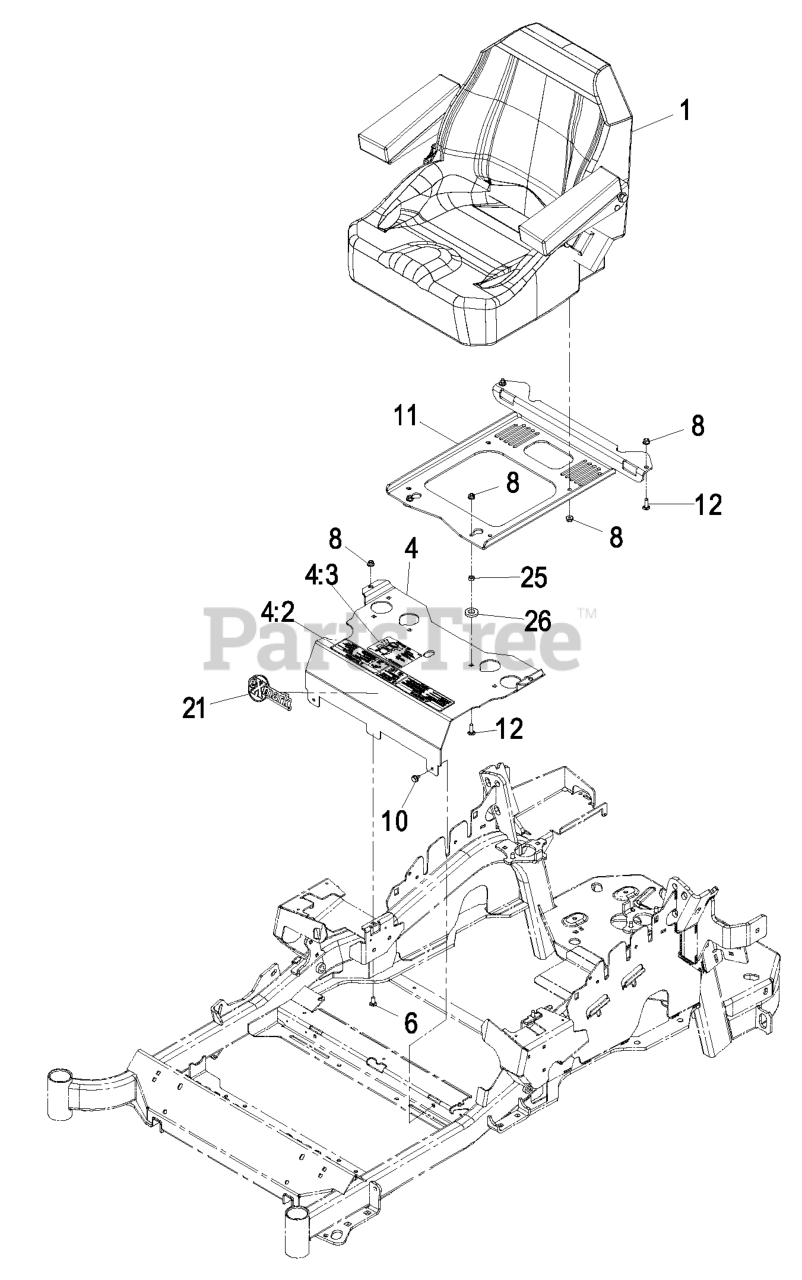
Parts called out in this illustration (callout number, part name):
4	MOUNT-SEAT
4:2	DECAL-CONSOLE
4:3	DECAL-SERVICE AID
6	SCREW-CARR
8	NUT-HF, NI
11	PLATE-SUPPORT, SEAT
12	SCREW-CARR
25	NUT-HEX
